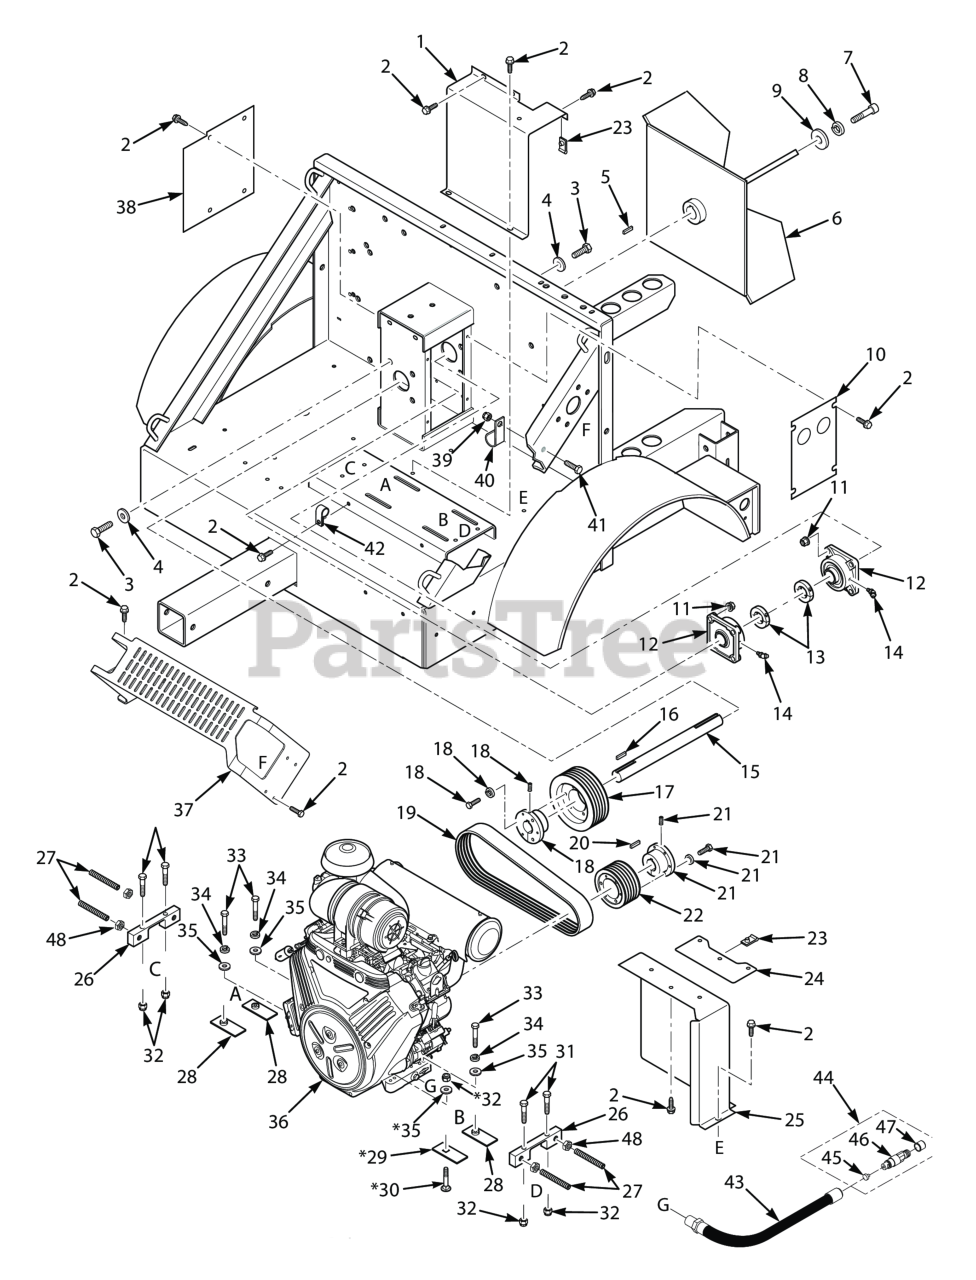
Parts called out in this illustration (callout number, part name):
1	Belt Cover, Front
2	Screw, Hex Head 5/16-18 x 3/4" Self Tap
3	Bolt, Hex Head 1/2-13 x 1-3/4"
4	Flat Washer, 1/2 (.562 x 1.375 x .109)
5	Key, 3/8 x 3/8 x 4-1/2"
6	Impeller, STL 4 Blade - 24-3/4" OD
7	SHCS, 5/8-18 x 2-1/2"
8	Lockwasher, 5/8" Spring
9	Flatwasher, 5/8-.688 x 1-3/4 x .134 HD
10	Belt Cover, LH - Gas
11	HEX LOCKNUT, ELASTIC STOP, 1/2-13
12	Bearing, Flange Mount
13	Collar. 2 pc 1-7/16
14	Grease Fitting
15	Shaft, Impeller - TLB25
16	Key, 3/8 x 3/8 x 2-1/4"
17	Pulley, Sheave 3v6.9 x 5 SK
18	Bushing, Taper - SK 1-7/16" (incl. hardware)
19	Belt, R3V x 450-5
20	KEY, 3/8 X 1-1/4
21	Hub, Taper - SDS 1-7/16 (incl. hardware)
22	Pulley, Sheave 3v6.9 x 5 SK
23	U-Nut, 5/16-18
24	Belt Guard, Engine
25	Belt Guard, Rear
26	Block, Engine Adjusting
27	SET SCREW, 1/2-13 X 4 HEX SOCK
28	Nut Plate Weldment - Briggs (x3)
28	Nut Plate Weldment - Kohler (x4)
29	Nut Plate - Briggs (x1)
30	Bolt, Carriage 5/16-18 x 5/16-18 x 2-1/4"
31	BOLT, HEX HEAD, 5/16-18 X 2-1/4
32	HEX NUT, ELASTIC STOP LOCK, 5/16-18
33	BOLT, HEX HEAD, 5/16-18 X 2-1/4
33	Capscrew, Hex Head 3/8-16 x 2.0"
34	Lockwasher, 5/16 (.317 x .586 x .078) Helical Spring
34	Lockwasher, 3/8" Spring, Kawasaki FX / FS
35	Flatwasher, 5/16-.375 x .875 x .083 (35BV & 37BV-EFI)
35	Flatwasher, 3/8" Special (.391 x .938 x .105)
36	Engine, Briggs Vanguard 35BV (not available through Scag Power Equipment)
36	Engine, Kohler Command 37CH (not available through Scag Power Equipment)
37	Muffler Guard (Briggs BV)
37	Muffler Guard Weldment (Kohler CH)
38	Belt Guard, RH - Gas
39	HEX NUT, ELASTIC STOP LOCK, 3/8-16
41	Bolt, Hex Head, 3/8-16 x 3/4"
42	Clamp, Double Cable 5/8" ID.
43	Hose, OIl Drain, Briggs & Stratton
43	Hose, Oil Drain - Kohler (incl. # 45, 46, 47,)
44	Valve Assembly, Oil Drain
46	O-Ring
47	O-Ring
48	NUT, HEX #10-32
